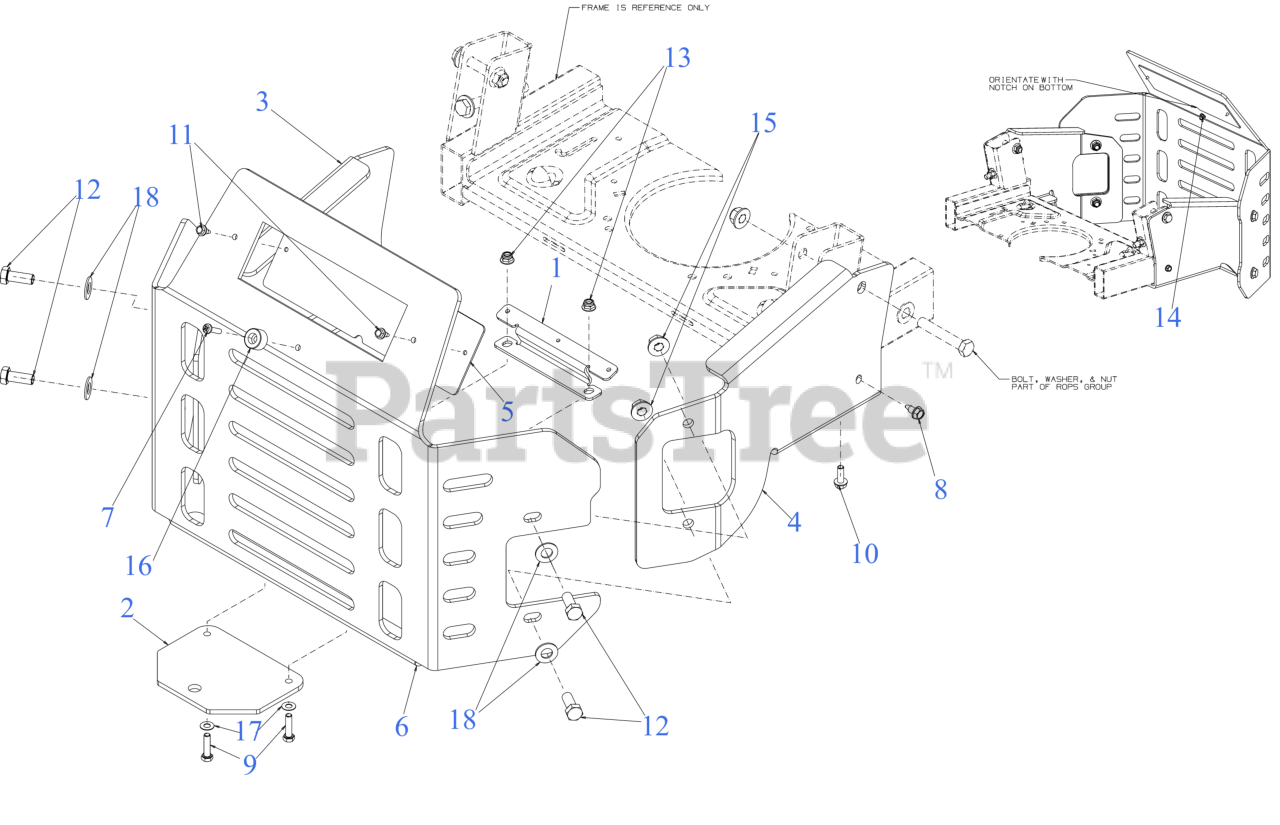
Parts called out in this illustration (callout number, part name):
1	MUFFLER BRACKET
2	HITCH PLATE
3	BUMPER BRACKET (LH)
4	BUMPER BRACKET (RH)
5	LOGO BUMPER PLATE
6	REAR BUMPER
7	MACHINE SCREW 1/4-20:1
8	SCREW 5/16-18 x .750
9	SCREW 5/16-18 x 1.25 GR5
10	SCREW 5/16-18 x .875 GR5
11	SCREW 1/4-20X.625
12	SCREW 1/2-13 x 1.25 GR5
13	FLANGE LOCK NUT 5/16-18
14	FLANGE LOCK NUT
16	BUMPER
17	FLAT WASHER
18	FLAT WASHER
